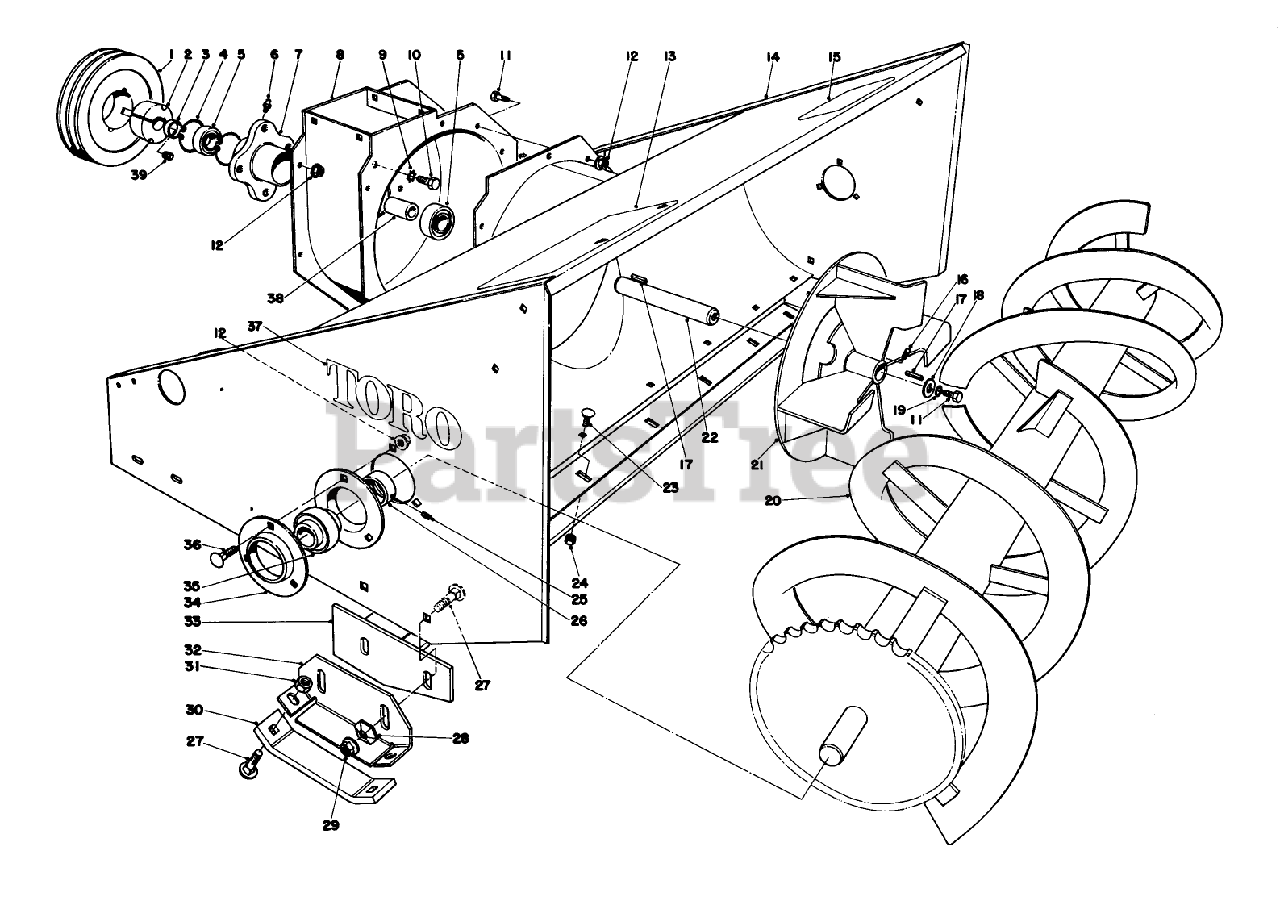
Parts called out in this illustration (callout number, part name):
1	TAPERLOCK PULLEY
2	Taper Lock Bushing (Incl. Ref. #39)
3	SPACER
4	RETAINING RING
5	BEARING
6	FITTING-LUBE, 45 DEG
7	SPINDLE HOUSING
8	BLOWER HSG WA
9	WASHER-LOCK, EXT
10	SCREW-HH
11	SCREW-HH
12	NUT-HF
13	Decal-Rear Weight
14	Auger Housing
15	Decal-Warning
16	SCREW-SET
17	Square Key
18	WASHER
19	WASHER-LOCK
20	Auger
21	IMPELLER WA 60096
22	IMPELLER SHAFT
23	SCREW-CARR
24	NUT-LOCK, NI
25	SCREW-SET, HSH
26	COLLAR-LOCK, BEARING
27	BOLT-CARR
28	LOCKWASHER-PYRAMID
29	FLANGE NUT W/LG FLG
30	SKID SHOE R
31	NUT-LOCK, CONE
32	SKID MTG PLT
33	SCRAPER WA
34	FLANGE
35	Bearing (Incl. Ref. #25 & 26)
36	SCREW-CARR
37	DECAL
38	SLEEVE 16107
39	SCREW-SET
